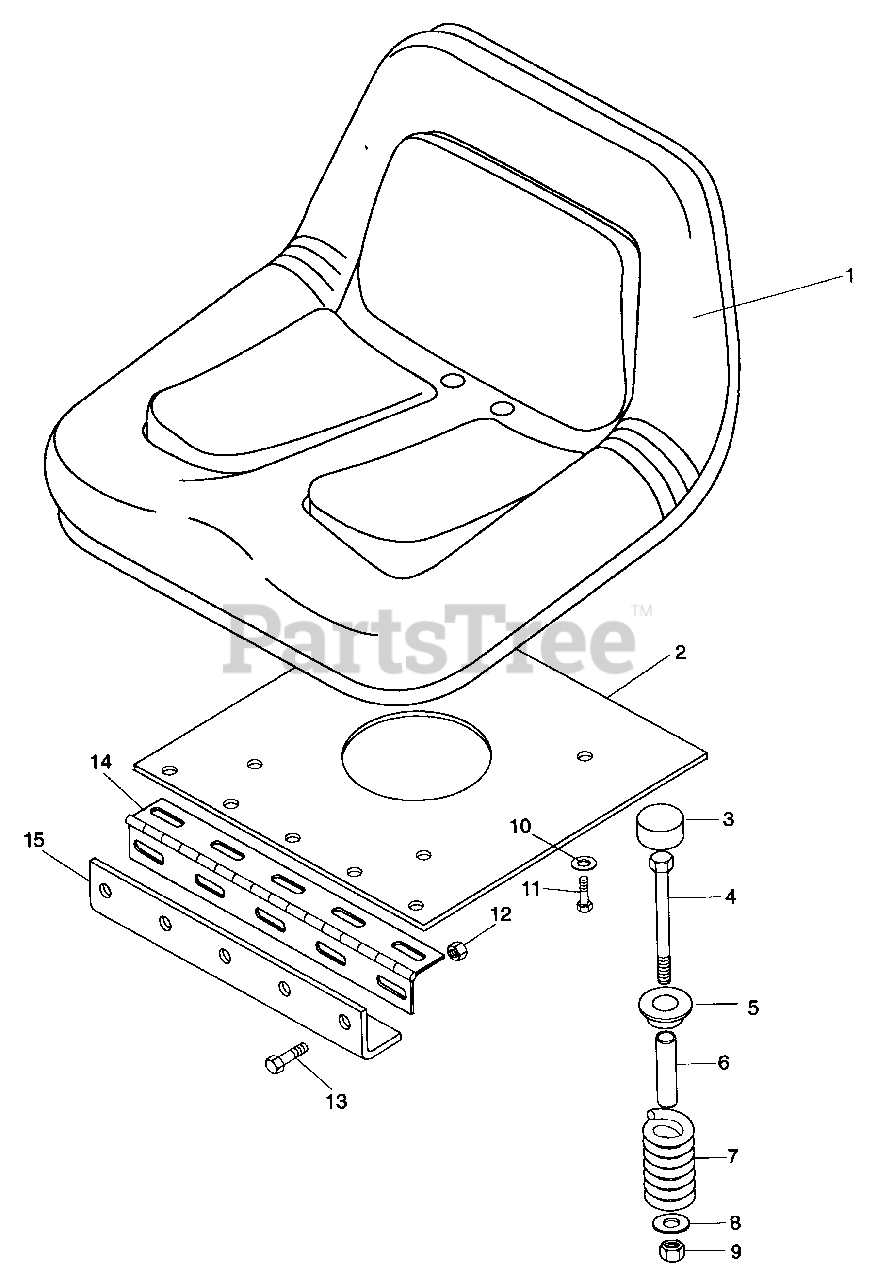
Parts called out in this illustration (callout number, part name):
1	SEAT HIGH BACK
2	PLT, SEAT MTG
3	TIP, RUBBER
4	BLT - HEX .25 - 20 X 2.25
5	CAP, VALVE SPRING
6	BUSHING, SPLIT ROLLED
7	SPRING, COMP LEE LHC-148J-O
8	WSHR-FL STL .344 X .688 X .065 PL
9	NUT - LK - NYL .250 - 20 PL
10	WSHR, LOCK .313 X .078 PL
11	BLT - HEX .31 - 18 X .625 GR 5
12	NUT - LK - NYL .312 - 18 PL
13	BLT - HEX .31 - 18 X .625 GR 5
14	HINGE
15	BRKT, SEAT SUPPORT
